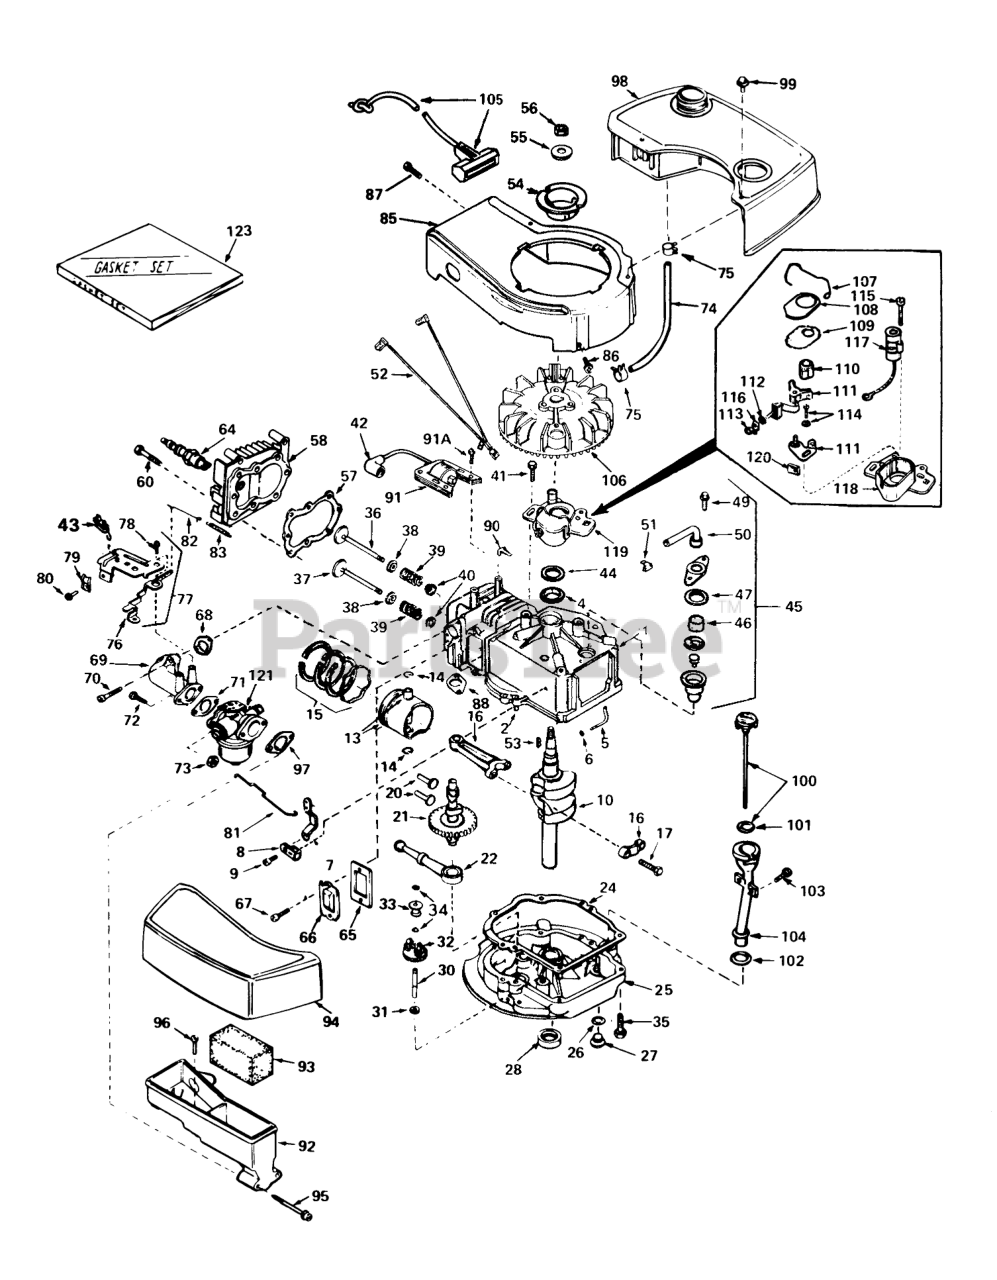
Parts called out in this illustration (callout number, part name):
1	Cylinder Assy. (Incl. Ref. #2 & 4)
2	Pin-Dowel
4	Seal-Oil
5	Rod, Governor (Incl. Ref. #6)
6	Washer-Flat
7	Governor Lever
8	Clamp-Lever, Governor
9	Screw
10	Crankshaft
13	Piston & Pin Assy. (Incl. Ref. #14) (Std.)
13	Piston, Pin & Ring Assy. (Incl. Ref. #14 & 15) (Std.)
13	Piston & Pin Assy. (Incl. Ref. #14) (.010 Oversize)
13	Piston Pin & Ring Assy. (Incl. Ref. #14 & 15) (.010 Oversize)
13	Piston & Pin Assy. (Incl. Ref. #14) (.020 Oversize)
13	Piston Pin & Ring Assy. (Incl. Ref. #l4 & 15) (.020 Oversize)
14	Ring-Retaining, Piston Pin
15	Ring Set Piston (Std.)
15	Ring Set Piston (.010 Oversize)
15	Ring Set Piston (.020 Oversize)
16	Rod Assy., Connecting (Incl. Ref. #17)
17	Bolt-Rod, Connecting
20	Lifter-Valve
21	Camshaft(Mech.Comp. Release)
22	Oil Pump ASM
24	Gasket, Mounting
25	Flange Assy., Mounting (Incl. Ref. #26 thru 30)
26	Gasket-Oil Drain
27	Plug Oil Drain
28	Seal Oil
30	Shaft-Governor
31	Washer-Flat
32	Gear Assy., Governor (Incl. Ref . #31)
33	Spool-Governor
34	Ring-Retaining
35	Screw (1/4-20 x 1-1/4)
36	Valve Intake (Std.) (Incl. Ref. #38, 39 & 40)
36	5B Valve, Intake (1/32" Oversize) (Incl. Ref. #38, 39 & 40)
37	Valve, Exhaust (Std.) (Incl. Ref. #38, 39 & 40)
37	Valve, Exhaust (1/32" Oversize) (Incl. Ref. #38, 39 & 40)
38	Cap-Upper Valve Spring
39	Spring-Valve
40	Cap-Valve, Spring
42	Cover-Spark Plug
43	Terminal
44	Gasket Stator
45	Breather Assy. (Incl. Ref. #46, 47, 49, 50 & 51)
46	Element-Breather
47	Gasket-Breather
49	Screw, Hex Hd. w/Conical
50	Tube, Breaker
51	Clip, Breather
52	Wire Ground
53	682488 LB GRASS HI-
54	Hub-Starter
55	Washer-Belleville
56	Nut-Flywheel
57	63573 GIL 42 SNWTHW
58	Head-Cylinder
60	Screw
64	Plug, Spark (J17LM or equiv.)
64	Plug, Spark (Champion RCJ-8)
65	Gasket-Breather
66	Cover-Valve
68	Gasket, Intake
69	Pipe, Intake
70	Screw (1/4-20 x 1)
71	Gasket-Carburetor
72	Screw (1/4-28 x 7/8)
73	Nut and Lock Washer (1/4-28)
74	Line-Fuel
75	Clamp-Line, Fuel
76	Lever Control
77	Control Assy., Speed (Incl. Ref. #43, 76 & 78)
78	Screw, Hex Washer Hd Shoulder Self-Tap
79	Conduit
80	Screw (10-32 x 3/8)
81	Link-Throttle
82	Link Governor Spring
83	Spring Governor
85	Housing Blower
86	Screw
87	Screw (10-24 x 9/16)
88	Gasket Exhaust
90	Clip-Wire
91	Lamination & Coil Assy. (Incl. Ref. #42)
91A	Screw
92	Body Air Cleaner
93	Filer, Air
94	Cove, Air Cleaner
95	Screw Fil Hd.
96	Screw, Hex Hd.
97	Gasket-Air Cleaner
98	Tank, Fuel
99	Screw (10-32 x 35/64)
100	Dipstick, Oil (Incl. Ref. #101) (Twist Lock)
103	Screw (10-32 x 1/2)
104	Tube-Oil Fill
105	Rope Assy., Starter
106	FIywheel
107	Spring Breaker Box
108	Cover-Dust
109	Gasket-Dust Cover
110	Cam-Breaker
111	Breaker Assy.
114	Breaker Screw
115	Condenser Screw
116	Terminal, Ground
117	Condenser
118	Stator Plate
119	Stator Plate Assy. (Incl. Ref. #107, 111 thru 118 & 120)
120	Felt,Cam Wiper
121	Carburetor (Incl. Ref. #71)
123	53024/VAR.16HP O/P
